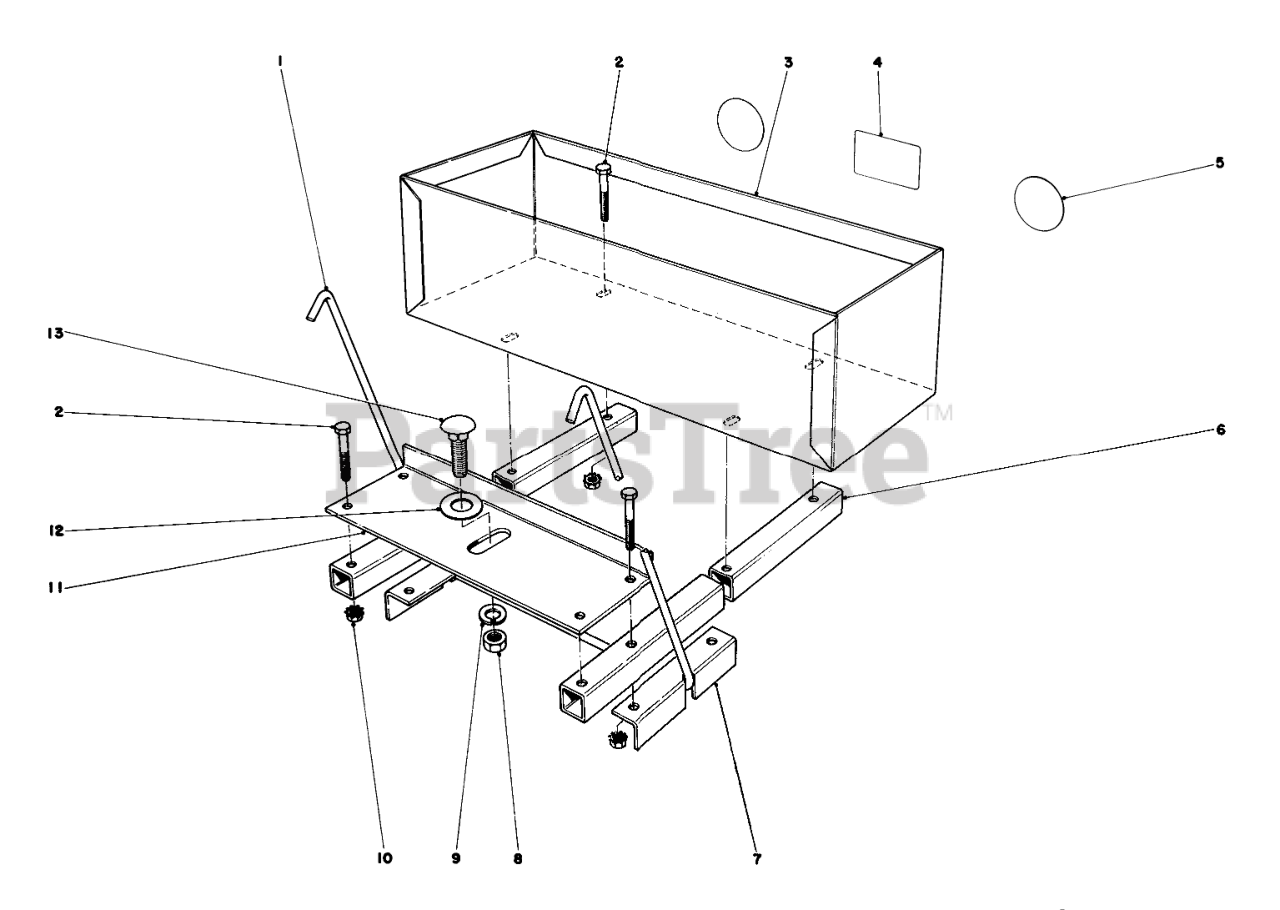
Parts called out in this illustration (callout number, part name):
1	Bracket-Support
2	SCREW-HH
3	Weight Box
4	Decal-Weight Box
5	Reflector
6	Tube-Mounting
7	Bracket-Mounting
8	NUT-HEX
9	WASHER-LOCK
10	NUT-KEPS
11	Bracket-Mounting
12	Washer
13	SCREW-CARR
